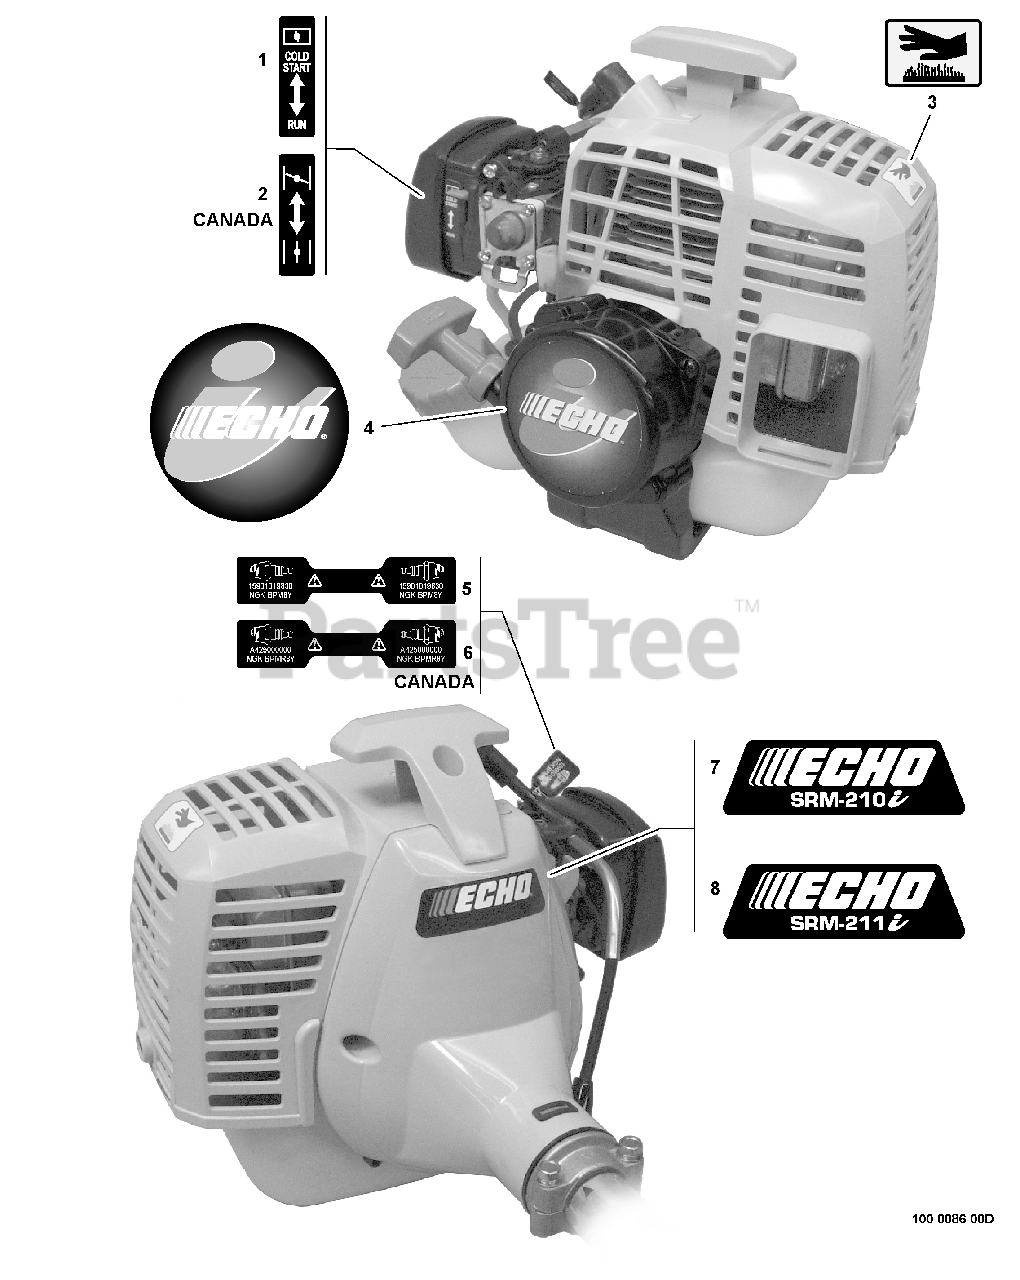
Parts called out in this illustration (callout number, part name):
1	LABEL - CHOKE
2	LABEL - CHOKE
3	LABEL - HOT SURFACE
4	LABEL - ECHO -- i
5	LABEL - SPARK PLUG -- BPM-8Y
6	LABEL - SPARK PLUG -- BPMR-8Y
7	LABEL - MODEL SRM-210i
8	LABEL - MODEL SRM-211i
